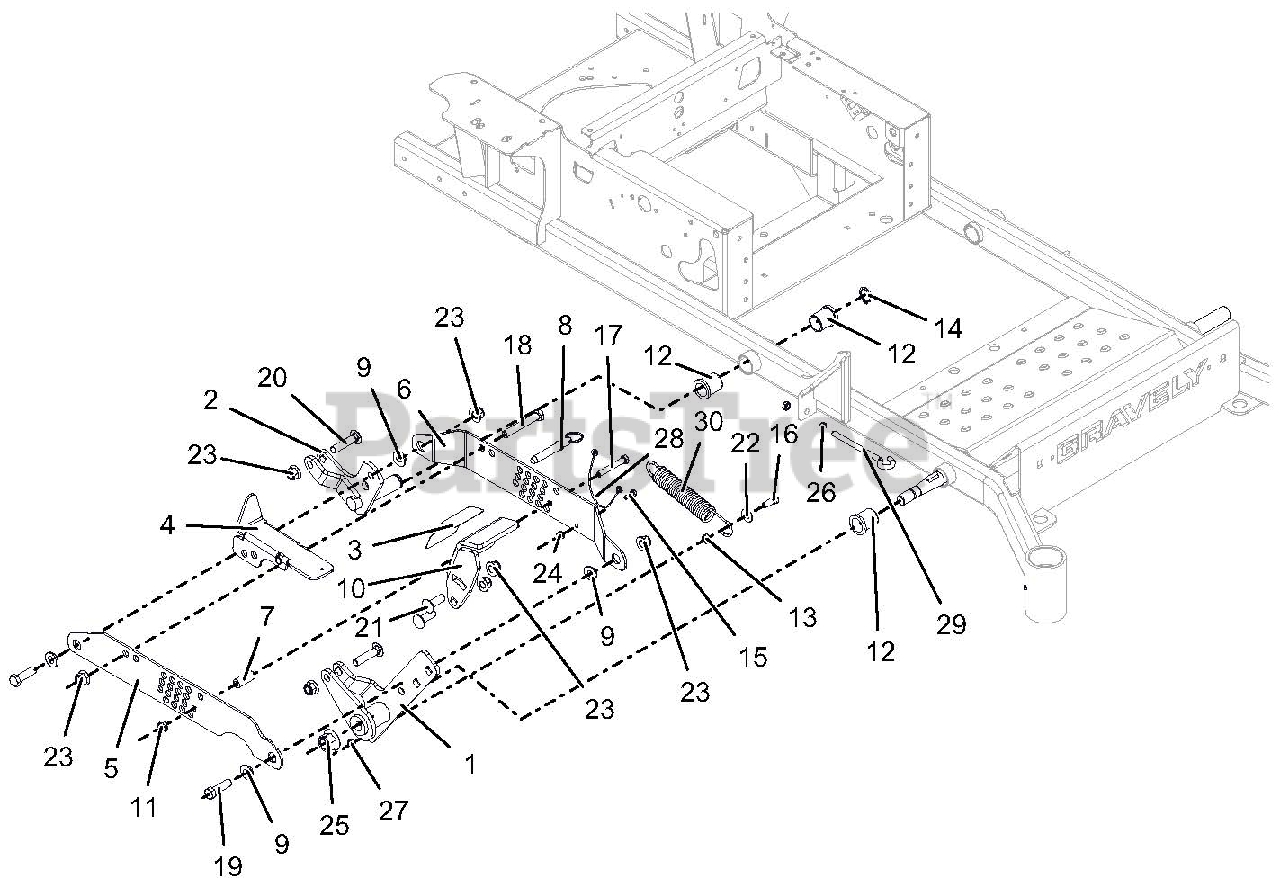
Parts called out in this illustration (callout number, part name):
1	WLDMT, TAPERED LIFT ARM FRONT LH-BLACK
2	WLDMT, RH REAR DECK LIFT
3	GRIP, PEDAL 1.50 X 3.00
4	WLDMT, MECHANICAL LOCK-UP-BLACK
5	BRKT, RH OUTBOARD LIFT/CUT HEIGHT-BLACK
6	BRKT, RH INBOARD LIFT/CUT HEIGHT-BLACK
7	SPACER, .375 X .625 X 1.54
8	PIN, .50 X 2.00 USABLE LG BALL
9	BSHG, FLANGE .515X.750X.31X1.12
10	PEDAL, ADJUSTABLE FOOT LIFT-BLACK
11	NUT-LK-NYL-FLG .38-16 YWZC
12	BSHG-FLG 1.00X1.25X1.5X1.5
13	BSHG, SLV .377X.624X.235
14	RG-RTNG-EXT 1.00X.078
15	BLT-HEX .25-20X.75 GR5 YWZC
16	BLT-HEX .38-16X1.00 GR5 YWZC
17	BLT-HEX .38-16X2.50 GR5 YWZC
18	BLT-HEX .50-13X3.25 GR5 YWZC
19	BLT-HEX .50-13X1.75 GR5 YWZC
20	BLT-RDHDSQNK .50-13X2.25 G5 Y
21	BLT-RDHDSQNK .50-13X1.50 G5 YWZC
22	WSHR-FL-STL.438X1.00X.083 YWZC
23	NUT-LK-NYL-FLG .50-13 YWZC
24	NUT-LK-NYL-FLG .25-20 YWZC
25	NUT-LK-NYL-FLG .75-10 YWZC
26	NUT, JAM .375-16 YWZC
27	@NUT-LK-CTR-JAM .375-16 YWZC
28	LANYARD, 12"
29	BOLT, EYE .38-16X6.00 .62 DIA
30	SPRG, TENSION .162 X 1.250 X 8.250
